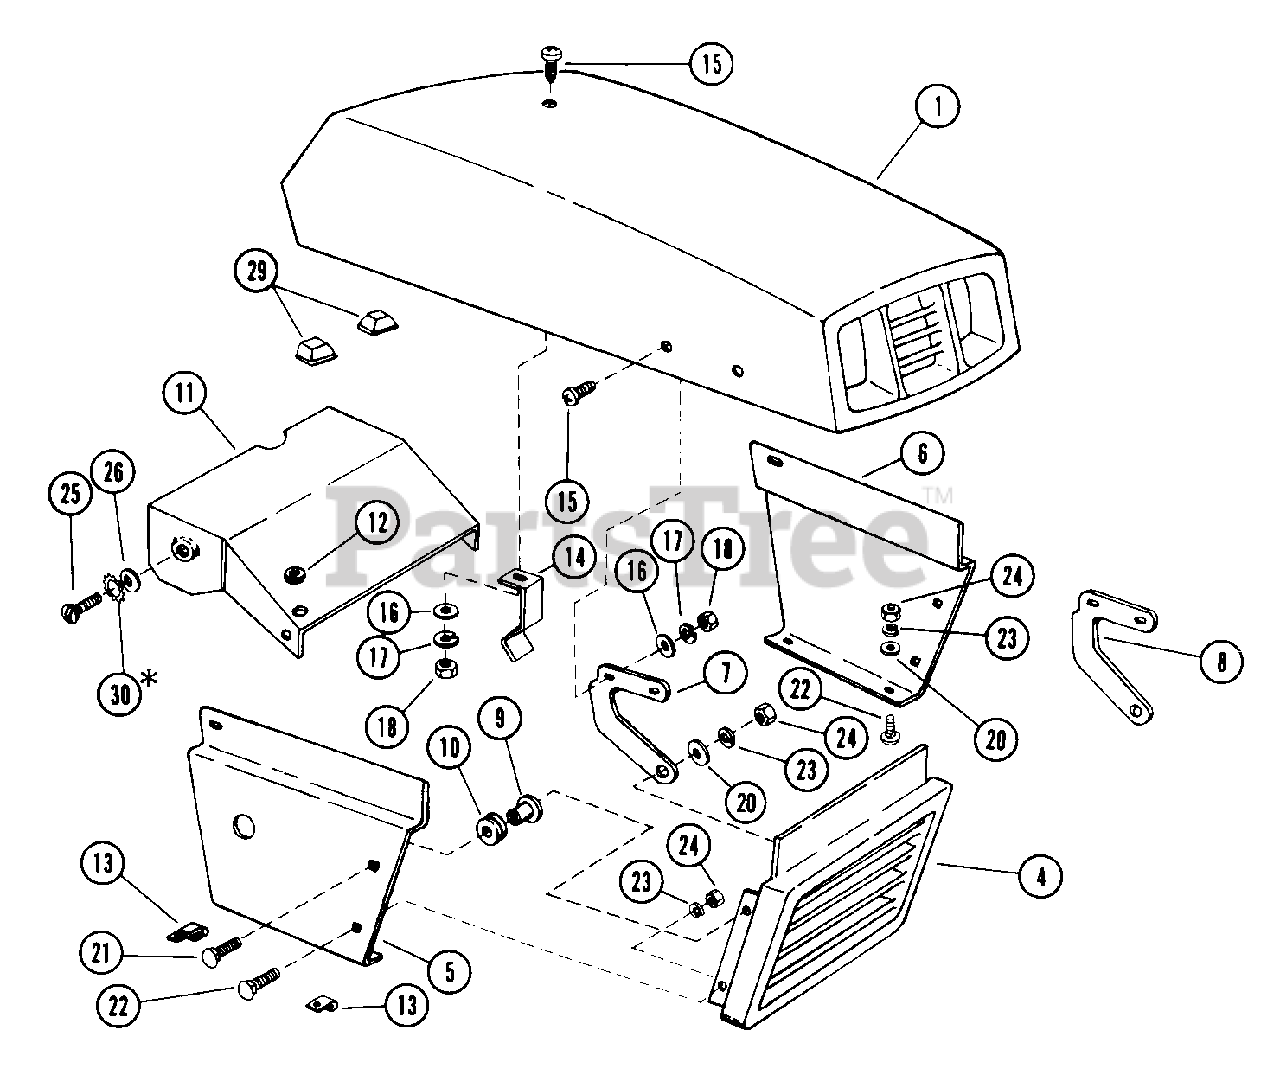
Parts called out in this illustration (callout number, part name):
1	HOOD & GRILL
5	SIDE SHEET R.H.
6	SIDE SHEET L.H.
7	R.H. HOOD HINGE
8	L.H. HOOD HINGE
9	SPACER -FLANGED .390X.500X.781
10	GROMMET .50IDX.812OD
11	MUFFLER SHIELD
12	GROMMET .438ID X .688 OD
13	J-CLAMP
14	HOOD STOP
15	SCR-MCH .25-20X.75 SLTR PL
16	WSHR-FL-STL.281X.62X.065 PL
17	WSHR-LK .250X.077 HVY PL
18	NUT-HEX .250-20 PL
20	WSHR-FL-STL .438X1.0X.083 PL
21	BLT-RDHDSQNK .38-16X2.00 SHTYW
22	BLT-RDHDSQSHNK .38-16X1.00 PL
23	WSHR-LK .375X.094 MED PL
24	NUT-HEX .375-16
25	SCR-MCH .31-18X.75 TSKBHD PL
26	WSHR-FL-STL.344X.688X.065PL
29	STOP
30	WSHR-LK-INT .313X.030 PL
